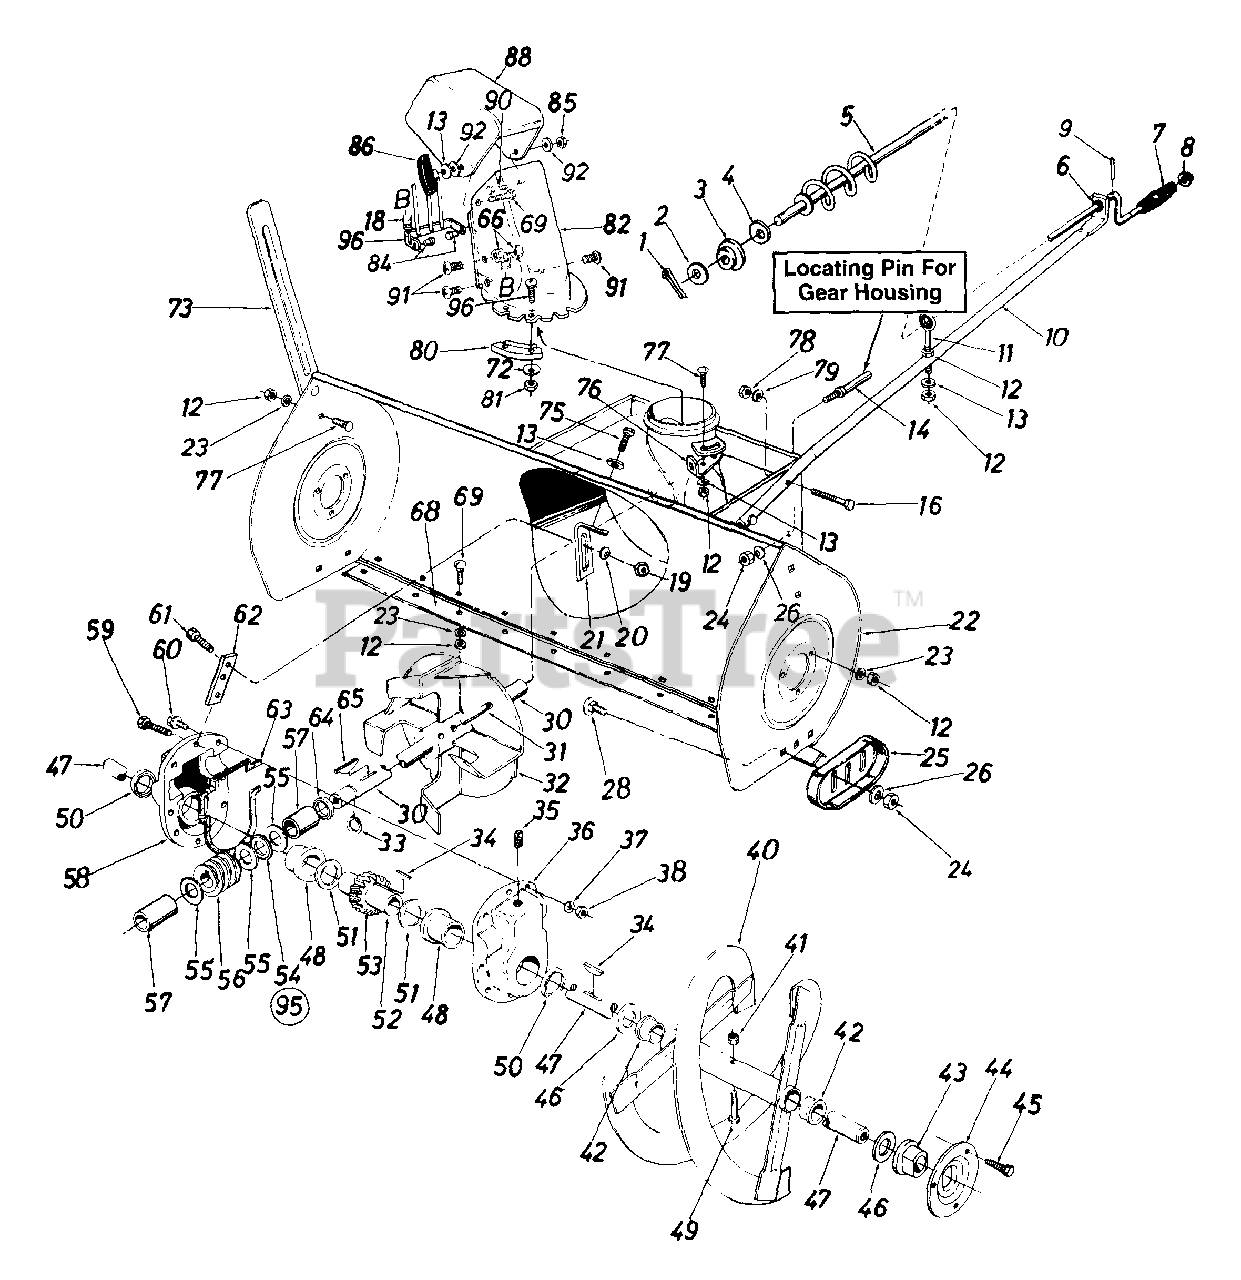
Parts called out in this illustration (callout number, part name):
1	Cotter Pin 3/32" x .75"
2	Fl-Wash 385" I.D. x 62" O.D. x .06"
3	Plastic Bushing .380" I.D.
4	Fl-Wash. 385" I.D. x .62" O.D. x .06"
5	Chute Crank Ass'y.
6	Plastic Bushing .38" I.D.
7	Knob - Black
8	Cap Speed Nut 3/8" Rod
9	Spring Pin
10	Chute Crank Supporting Tube
11	Eyebolt Chute Crank Support
12	Hex Nut 5/16-18 Thd.
13	Bell-Wash..345" I.D. x 88" O.D. x .06"
14	Belt Keeper Studs 3/8-16 x 2.75"
16	Hex Bolt 3/8-24 x 1.28" Lg.
18	Extension Spring
19	Hex Nut 1/4-28 Thd.
20	Bell-Wash..25" I.D. x .88" O.D x .062"
22	45" Snow Thrower Hsg. Ass'y.
23	L-Wash. 5/16" I.D.
24	Hex Jam Nut 3/8-16 Thd.
25	Reversible Slide Shoe
26	Bell-Wash..4" I.D. x .88" O.D. x .06"
28	Carr. Bolt 3/8-16 x .62" Lg.
30	Blower Axle 14.75" Lg.
31	Spr. Spiral Pin - H.D.
34	#91 Woodruff Key 1/4" x 3/4" Dia.
35	Plastic Vented Plug 1/4-18 Pipe Thd.
36	Gear Hsg. Half - L.H.
37	Shakeproof Spr. Wash.
38	Hex Ins. L-Nut 5/16-18 Thd.
41	Hex Ins. L-Nut 5/16-18 Thd.
42	Flange Bearing
43	Flange Bearing w/Flats
44	Bearing Housing
45	Hex Sems Bolt 5/16-18 x .75" Lg.
46	Fl-Wash.
47	Spiral Axle
48	Flange Bearing
49	Shear Bolt 5/16-18 x 1.75
50	Oil Seal 1.5" I.D. Garlock
51	Fl-Wash 1.5" I.D. x 2" O.D. x .03"
52	Worm Gear Shaft
53	Worm Wheel - L.H. Double Thd.
54	Thrust Brg. 88" I.D. x 1.44" O.D. x .078"
55	Fl-Wash 88" I.D. x 1.4" O.D. x .125"
56	Worm Gear - L.H. Double Thd.
57	Sleeve Brg..875" I.D.
58	Gear Hsg Half - R.H.
59	Hex Bolt 5/16-18 x 1.25" Lg
60	Hex Bolt 5/16 x 1" Lg
61	Hex Bolt 1/4-28 x .75" Lg.
62	Gear Hsg Support Plate
63	Rubber Gasket
64	Oil Seal for .875" I.D. Garlock
65	#9 Hi-Pro Key 3/16" x 3/4" Dia.- H T
66	Hex L-Nut 1/4-20 Thd.
69	Carr-Bolt 5/16-18 x 1" Lg.
72	Fl-Wash .281" I.D. x 5" O.D. x .063"
75	Hex AB-Tap Scr 5/16 x 75" Lg.
77	Carr Bolt 5/16-18 x 75" Lg.
78	Hex Nut 3/8-24 Thd.
79	L-Wash. 3/8" I.D.
80	Chute Flange Keeper
81	Hex L-Nut 1/4-20 Thd.
82	Lower Chute
84	Shld. Nut 1/4-20 Thd.
85	Hex L-Nut 5/16-18 Thd.
86	Hand Knob
88	Upper Chute
90	Truss Mach. Scr. 5/16-18 x 75" Lg.
91	Truss Mach. Scr. 1/4-20 x .5" Lg.
92	Fl-Wash..344" 1.0. x 1.125" O.D. x .125"
95	Gear Box Ass'y. Complete
96	Truss Mach. Scr. 1/4-20 x 3/4" Lg.
